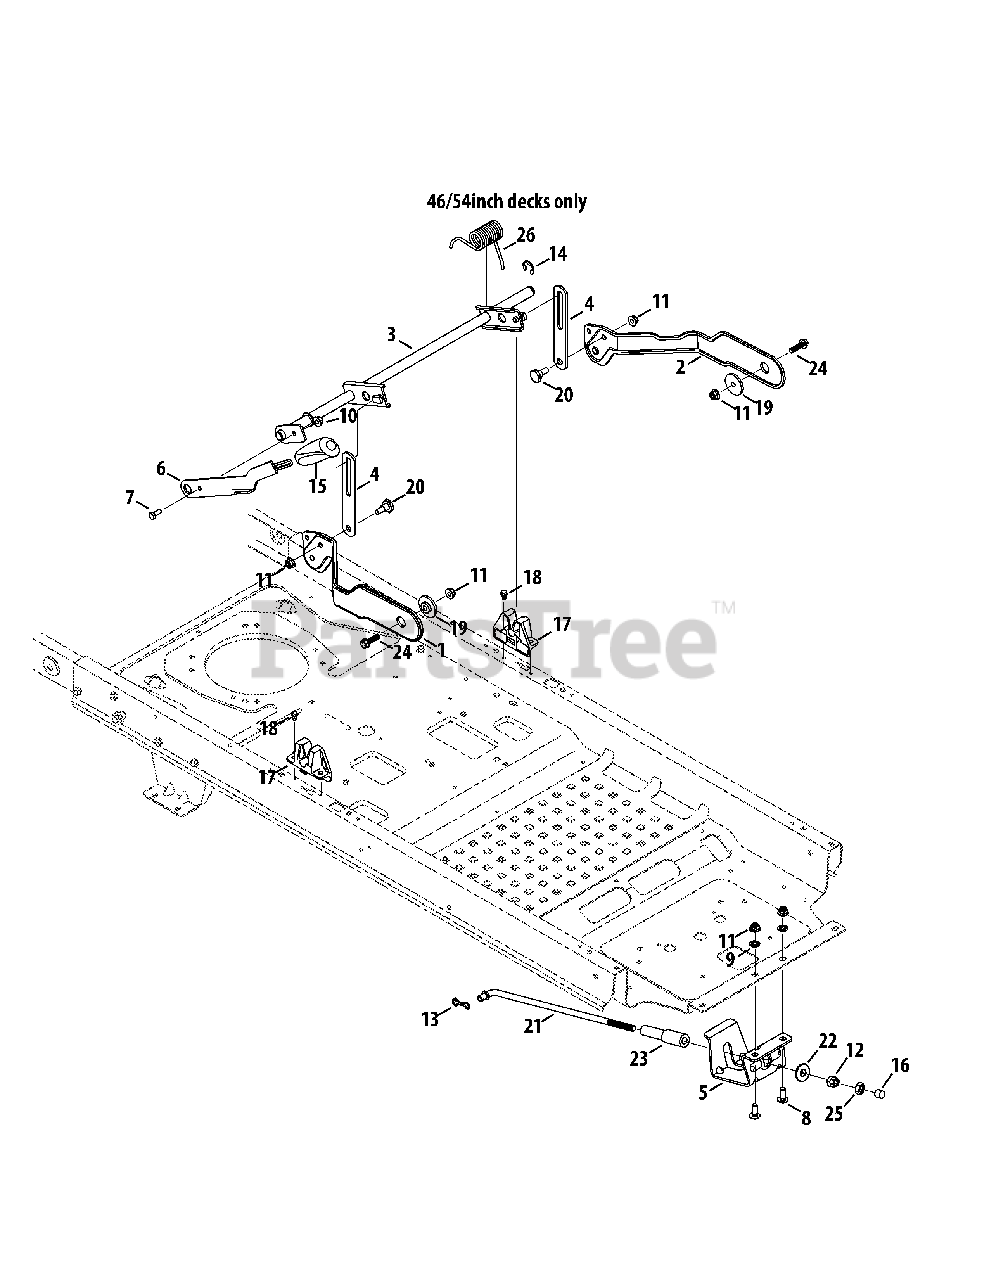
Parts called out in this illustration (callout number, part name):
1	Deck Lift Plate, RH
2	Deck Lift Plate, LH
3	Deck Lift Shift Assembly
4	Lift Link Plate
5	Rod Support Mounting Bracket
6	Deck Lift Handle
7	Hex Cap Screw, 5/16-18 x .75
8	Carriage Bolt, 3/8-16 x 1.00
9	Push Nut, 3/8
10	Flange Lock Nut, 5/16-18
11	Flange Lock Nut, 3/8-16
12	Hex Nut, 1/2-13
13	Bow-Tie Cotter Pin
14	E-Type Ring, .750
15	Grip, .50 ID
17	Deck Lift Bracket
18	Shoulder Screw, .500 x 1/4-20
19	Shoulder Spacer, .854 x .232
20	Shoulder Screw, .500 Dia. x .434
21	Deck Lift Rod
22	Deck Lift pivot Cup
23	Nylon Sleeve, .55 ID x 4.50 LG
24	Screw, 3/8-16 x 1.00
25	Jam Nut, 1/2-13
26	Torsion Spring, 1.323 ID x 2.83 LG
